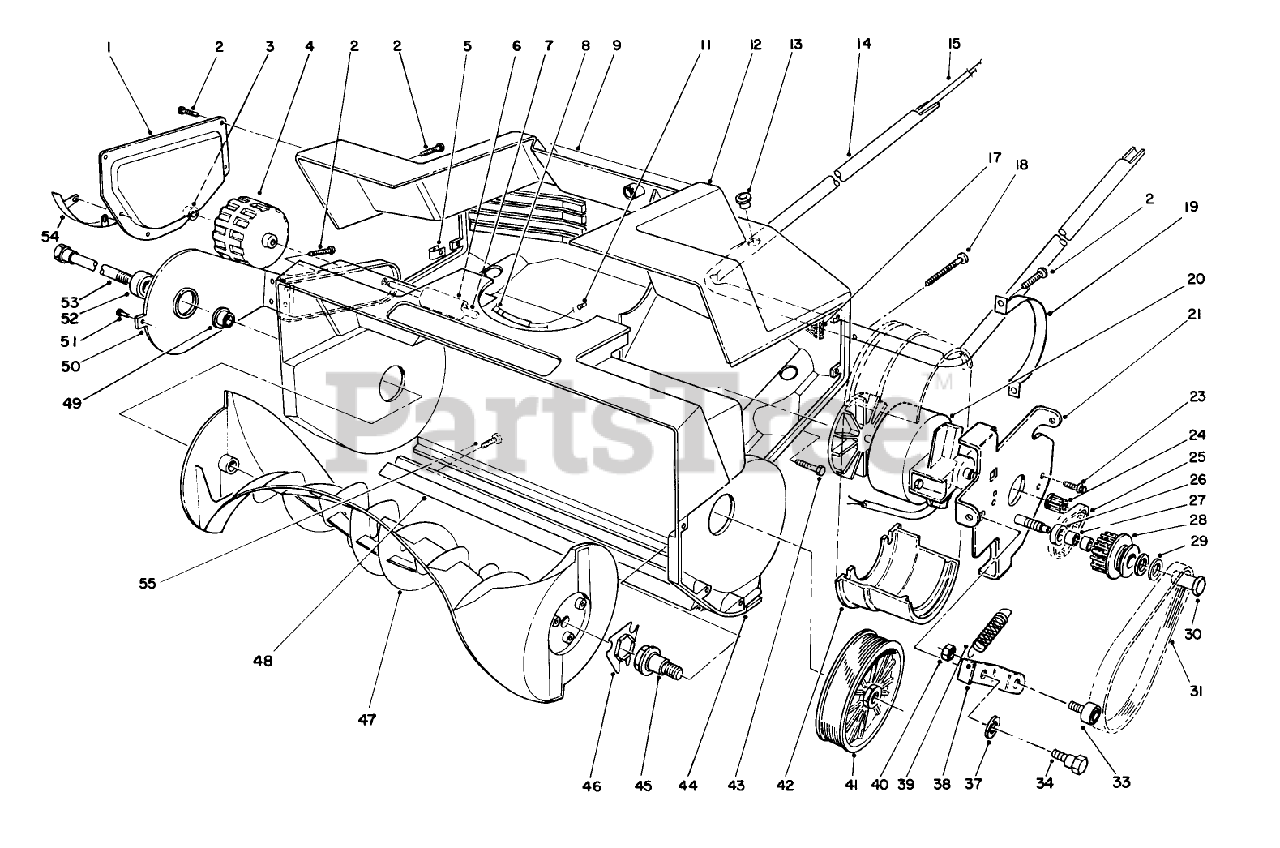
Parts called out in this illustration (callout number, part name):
1	PLATE - SIDE, PAINTED
3	PUSHNUT-CAP, WASHER
4	WHEEL, 1200/1800
7	AXLE SHAFT
8	STRAIN RELIEF-GRIPMASTR
11	CONNECTOR SCREW
12	SHROUD W/O AMP LABEL
13	BUSHING
17	FOAM FILTER
18	SCREW-PLASTIC, PPH
19	STRAP-MOTOR, FINISHED
20	MOTOR, 1800
21	PLATE - MOTOR ASSY.
23	TEKS SCREW
24	DRIVER PULLEY
25	BELT-PULLEY, IDLER/DRIVER
26	WASHER
27	DISC - ORD PULLEY
29	WASHER-THRUST
30	IDLER BOLT
33	IDLER BEARING
34	SCREW-SHOULDER
37	WASHER
38	IDLER BRACKET
39	IDLER SPRING
40	NUT-LOCK, NI
41	DRIVEN PULLEY
42	1800 CLAMP MTR BRCKT
43	SCREW-HWH THD CUT
44	ROTOR/HOUSING 1800
45	SHAFT, ROTOR DRIVE
46	COUPLER, ROTOR
47	ROTOR - 1800 SNOWBLOWER
48	SCRAPER - 1800
49	BUSHING
50	WHEEL BRKT ASSY/1800
51	RIVET-POP
54	SKID, 1800
